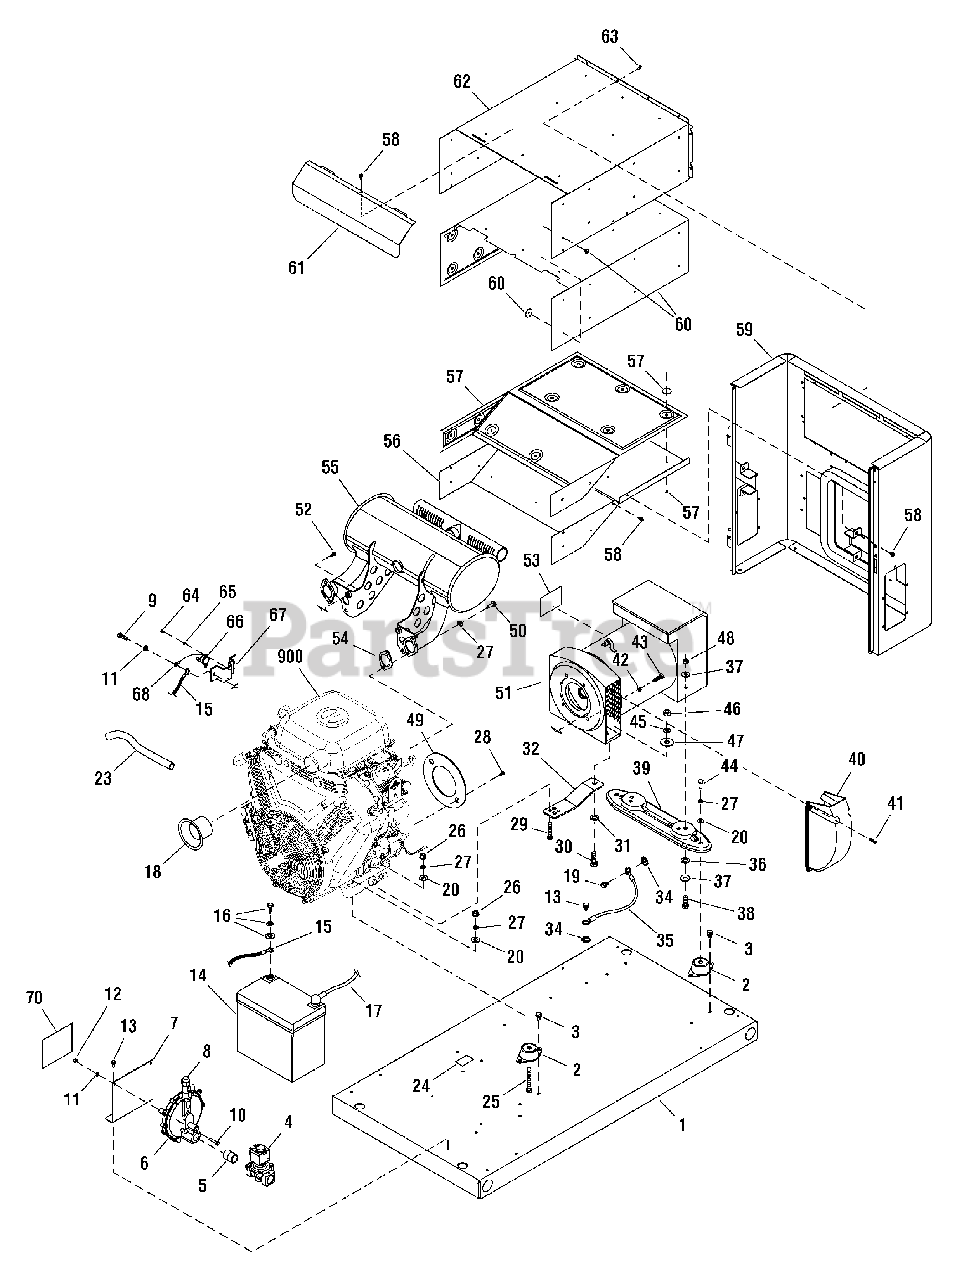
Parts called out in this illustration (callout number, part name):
2	MOUNT, Vibration
4	SOLENOID, Gas Fuel
6	REGULATOR, NG/LPG
7	BRACKET
9	* CAPSCREW, Hex, Head, M6-1 x 16
10	* CAPSCREW, Hex, Head, M6-1 x 30
11	* WASHER, Lock, 1/4
12	* NUT, M6-1
13	BOLT
16	KIT, Hardware, Battery
19	* CAPSCREW, Hex, Head, M6-1 x 12
20	* WASHER, Flat, 5/16-M8
23	HOSE, Oil Drain
24	DECAL
25	* CAPSCREW, Hex, Head, 5/16-18 x 2.5
26	* NUT, 5/16-18
27	* WASHER, Lock, 5/16-M8
28	* CAPSCREW, Hex, Head, 5/16-24 x 3/4
29	* CAPSCREW, Hex, Head, 5/16-18 x 2
30	* CAPSCREW, Hex, Head, M12-1.75 x 35
31	* WASHER, M12
34	* WASHER, Shakeproof, M6-1/4
36	* WASHER, Lock, M10
37	* WASHER, Flat, M10
38	* CAPSCREW, Hex, Head, M10-1.5 x 30
39	SUPPORT, Alternator
41	* SCREW, Phillips Head, M5-0.8 x 20
42	* WASHER, Lock, 3/8
43	* CAPSCREW, Socket Head, 3/8-16 x 1-1/4
44	* CAPSCREW, Hex, Head, 5/16-18 x 3/4
45	* WASHER, Lock, M12
46	* NUT, Hex, M12
47	* WASHER, Flat, M12
48	* NUT, M10
50	SCREW
51	ALTERNATOR, Complete
53	DECAL
59	BULKHEAD, Alternator
62	BOX, Muffler Top
64	* SCREW, Phillips Head, 4-40 x 0.19
65	* WASHER, Lock, #4
66	SWITCH, Temp
67	PLATE, Temp Switch
900	** ENGINE
